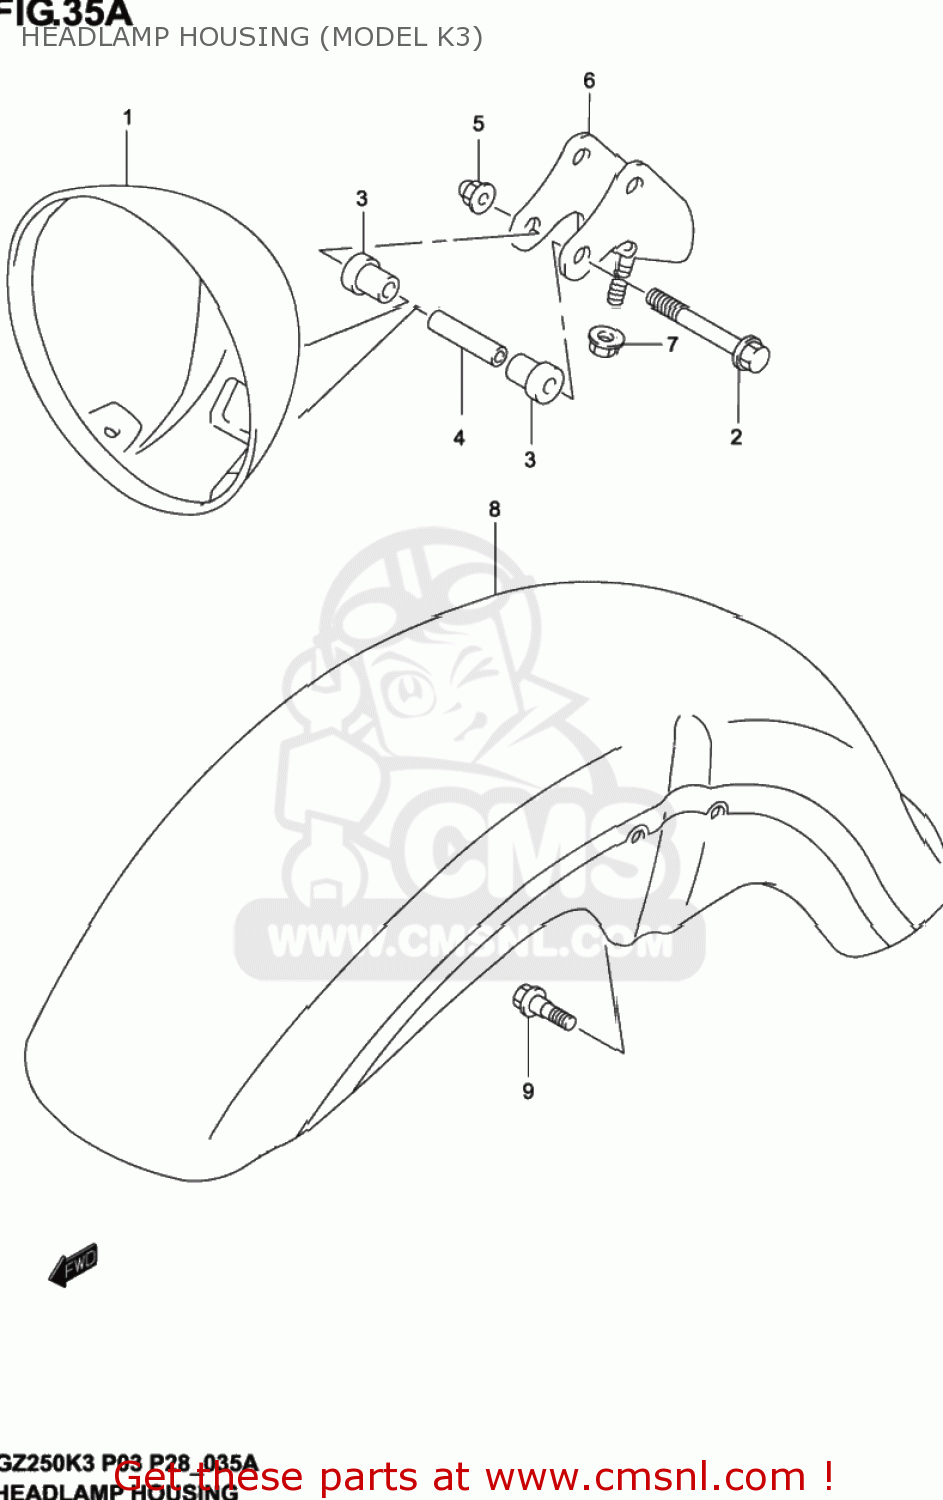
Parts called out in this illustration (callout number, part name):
1	HEADLAMPHOUSIN
2	BOLT
3	CUSHION,HEADLAMP HOUSING
4	SPACER(6.5X9X38.3)
5	NUT
6	BRACKET,HEADLAMP HOUSING
7	NUT
8	FENDER,FR
9	BOLT(6X16)
